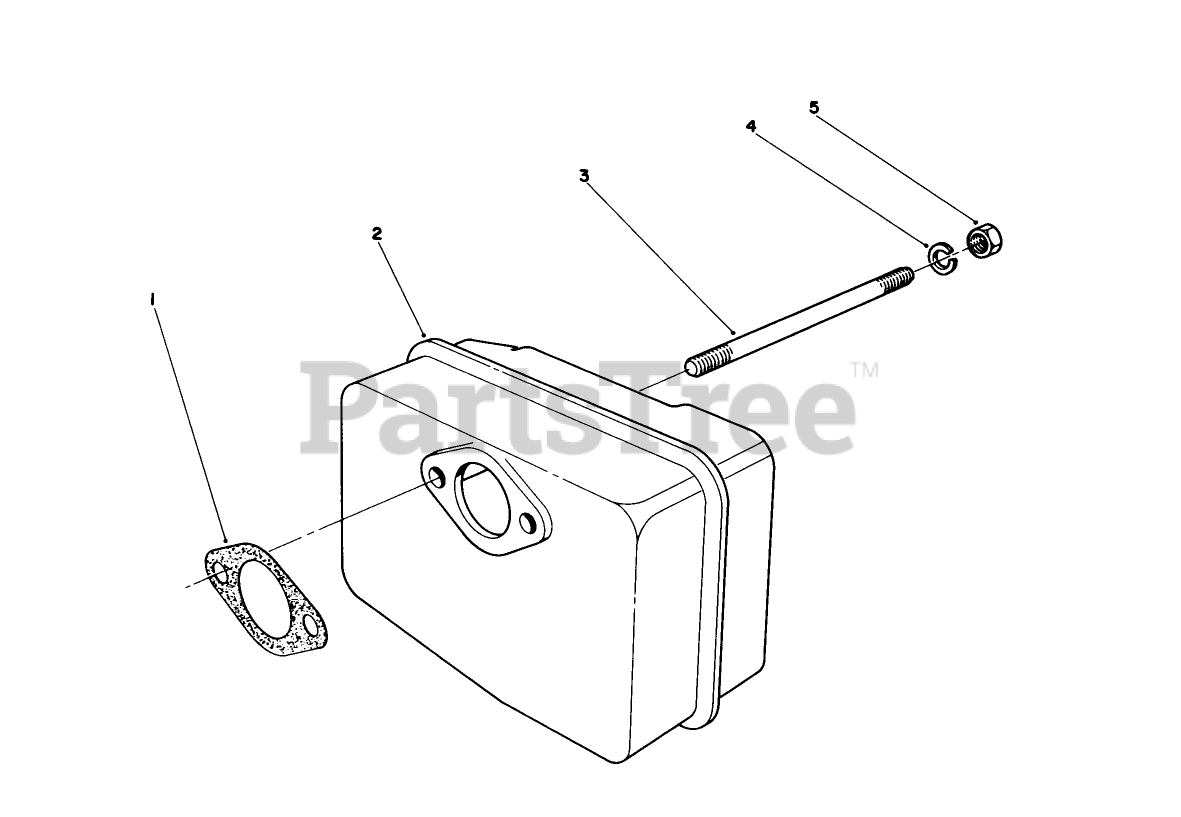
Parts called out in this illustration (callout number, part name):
1	GASKET
2	MUFFLER
4	WASHER-LOCK
